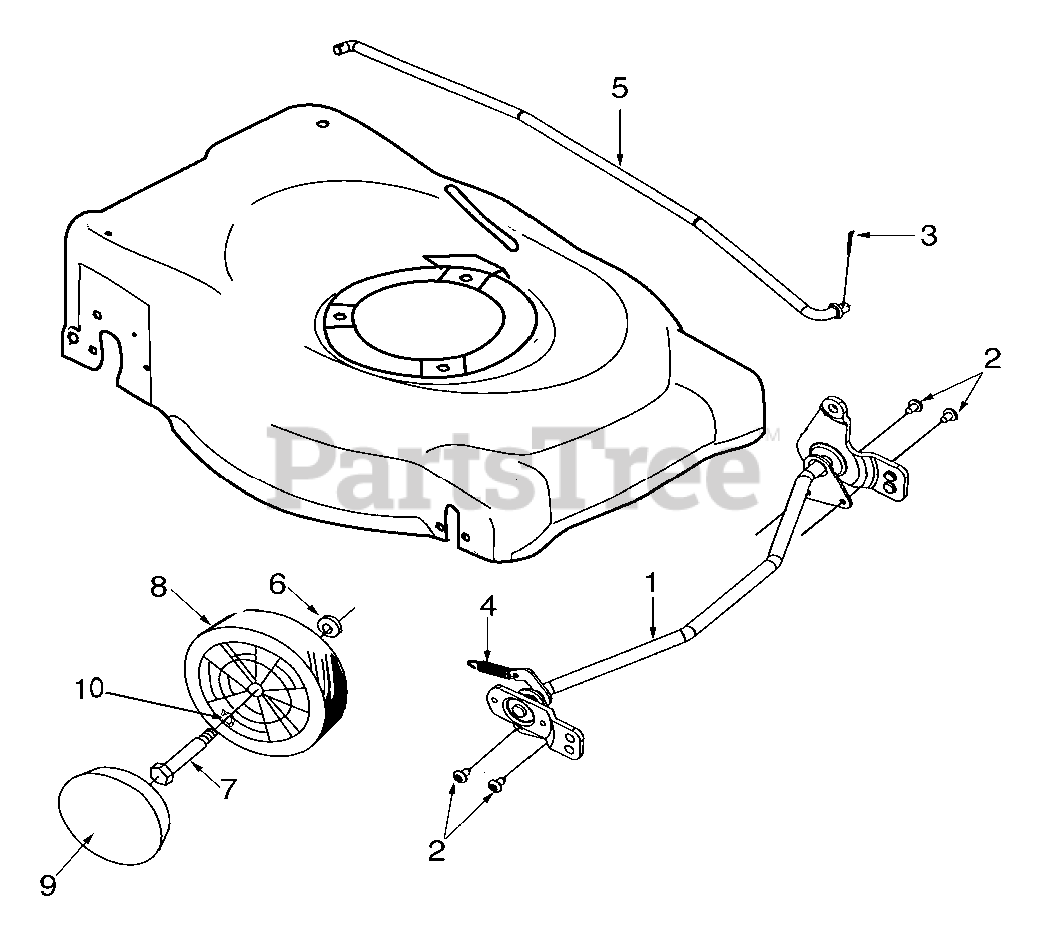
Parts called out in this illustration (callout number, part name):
2	AB Pan Scr. 1/4-14 x.50 Lg.
3	Cotter Pin.072 x 1.12 Lg.
4	Extension Spring
5	Adj. Rod
6	Bell Washer
7	Shl. Bolt.498 x 1.445 3/8-16
8	Wheel Ass'y - Complete
9	Hub Cap
10	Wave Washer
